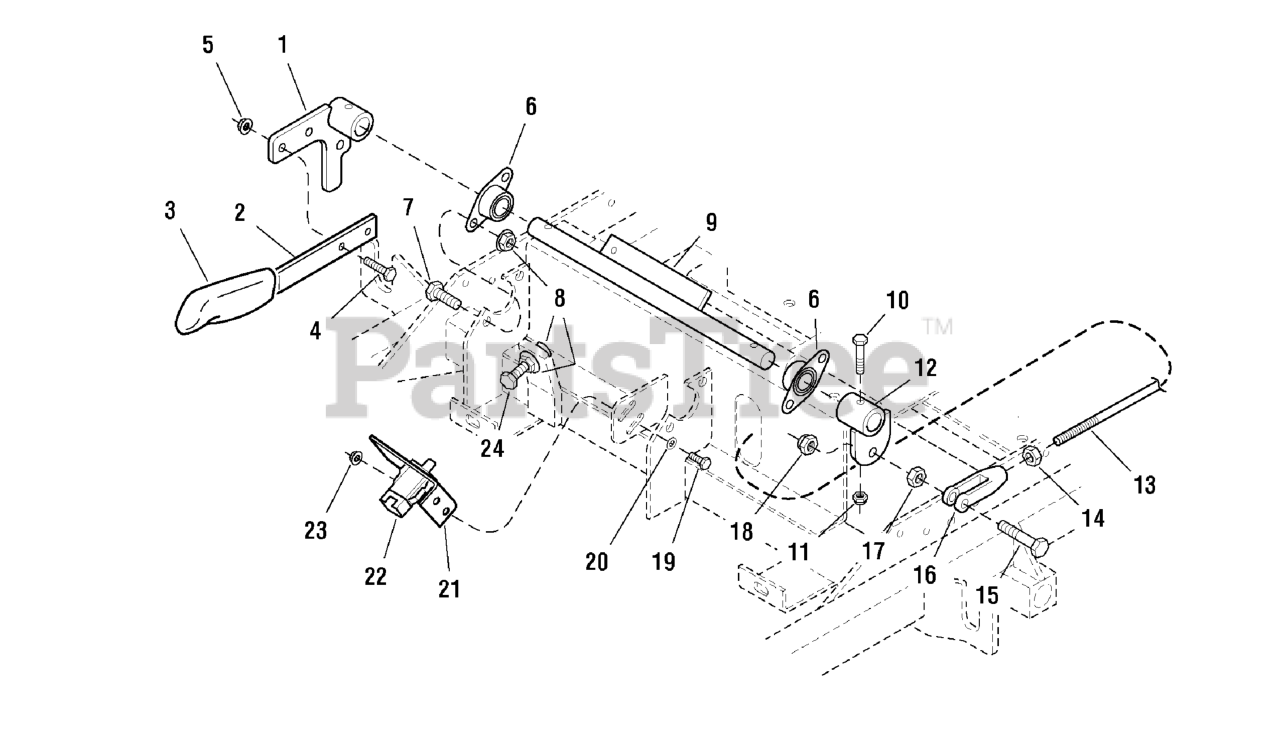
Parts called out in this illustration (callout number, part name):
1	BRAKE HANDLE MOUNT
2	BRAKE HANDLE
3	GRIP
4	BOLT, 5/16-18 X 1 GD5 YZ
5	NUT, 5/16-18 HEX SERRATED FLANGE (SMALL)
6	BEARING, Flange
7	BOLT, 3/8-16 X 3/4" GD5 CZ
8	NUT, 3/8-16 Hex Serrated Flange
9	BRAKE HANDLE SHAFT
10	BOLT, 1/4-20 x 1-3/4
11	NUT, 1/4-20 HEX NYLON LOCK
12	PIVOT, LINKAGE MOUNT WELDMENT - BLK
13	BRAKE CONNECTING ROD
14	NUT, 3/8-24 Hex
15	BOLT, 3/8-16 X 2, GD5, CZ
16	CLEVIS, 3/8-24, Plastic
17	NUT, 3/8-16 Hex
18	NUT, 3/8-16 HEX NYLON LOCK
19	BOLT, 1/4-20 x 3/4
20	WASHER, 1/4 SAE
21	SWITCH MOUNT BRACKET
22	SWITCH, DP NO/NC SNAP-IN
23	NUT, 1/4-20 HEX SERR. FLANGE
24	BOLT, 3/8-16 x 1-3/4 TFL
